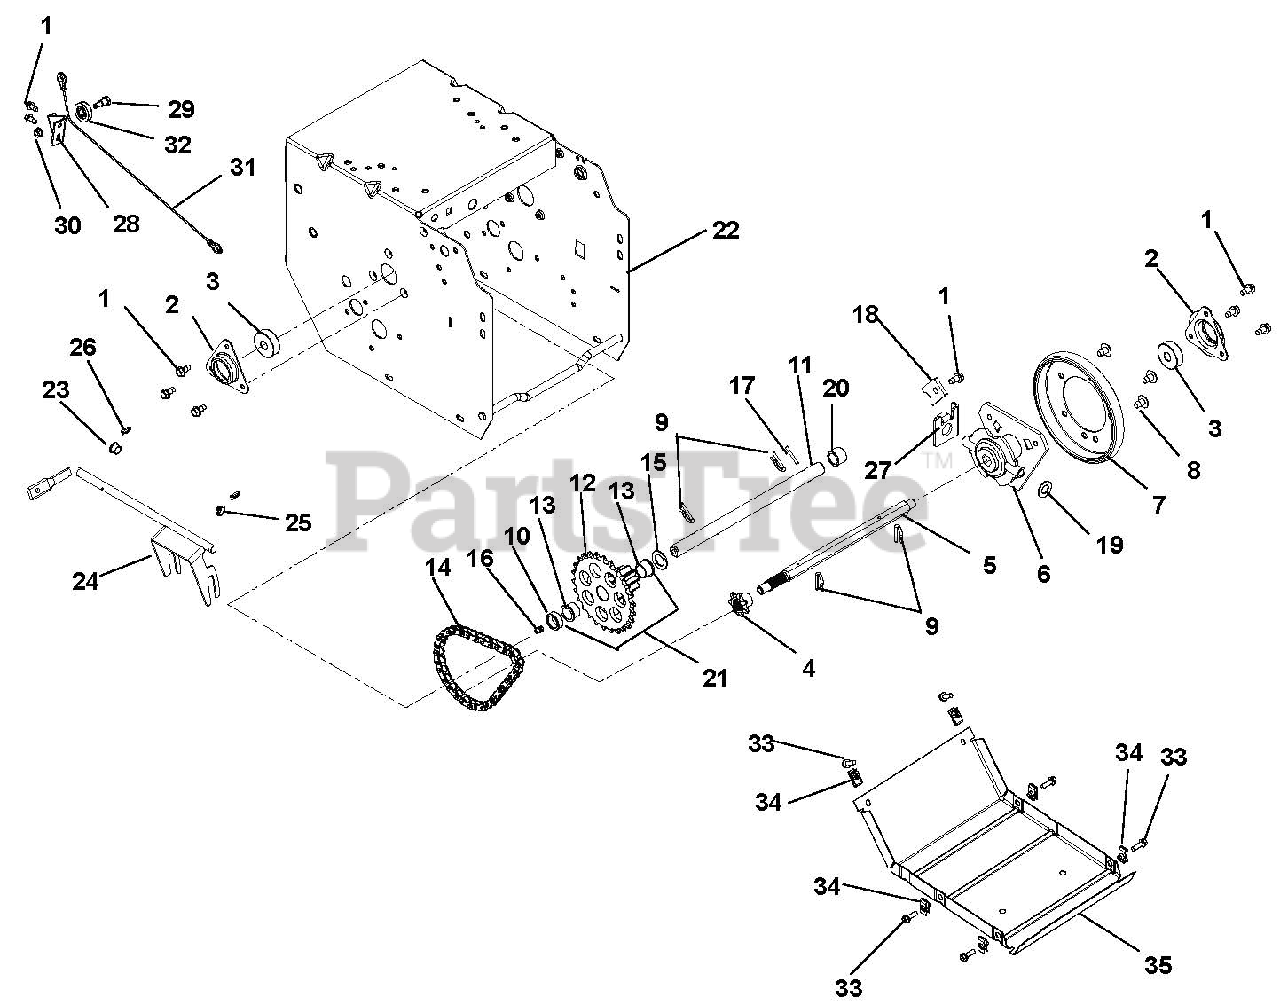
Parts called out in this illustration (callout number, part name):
1	SCR-TAP .25-20X.50 HWH TR YWZ
2	FLANGE, BEARING
3	BRG-BALL .437X1.375X.437
4	SPROCKET, PINION 7T W/SPLINE
5	SHAFT, HEX W/SPLINE TRACK
6	CARRIER, DRIVE DISK
7	FRICTION, DISC
8	SCR-TAP SERRDHDTX .31-18X.50BP
9	PIN, SPRING CLIP
10	BSHG-SLV, .635X.880X.305
11	SHAFT, PINION TRACK
12	PINION & SPROCKET
13	BSHG-FLG .625X.750X.500X.875
14	CHAIN - #41, 32 PITCHES
15	WSHR-FL-STL .630X1.005X.062 YZ
16	ZERK,FITTING .25X.125 DRIVE IN
17	@PIN-GRV .125X1.00 TP E ALLOY
18	TAB, ANTI ROTATION
19	WSHR-FL-STL .505X1.00X.062YWZC
20	SPACER, .635X.880X.611
21	PINION & SPROCKET W/BUSHINGS
22	FRAME, 920/921
23	BUSHING, POLYLINER-.50 SPLIT
24	WELDMENT, SHIFT FORK
25	BUSHING, POLYLINER-.50 SNAPIN
26	CLIP, SPRING
27	BRACKET, FORMED - SHIFT FORK
28	BRACKET, CABLE PULLEY
29	BOLT, SHLDR-.375X.375X.25-20
30	@NUT-LK-CTR-FLG .25-20 YWZC
31	CABLE, LOWER TRACTION (CMPCT)
32	PULLEY, CABLE
33	BLT-HEX .25-20X.75 HWH YZ GR5
34	NUT-RTNR .25-20X.56
35	COVER, BOTTOM
